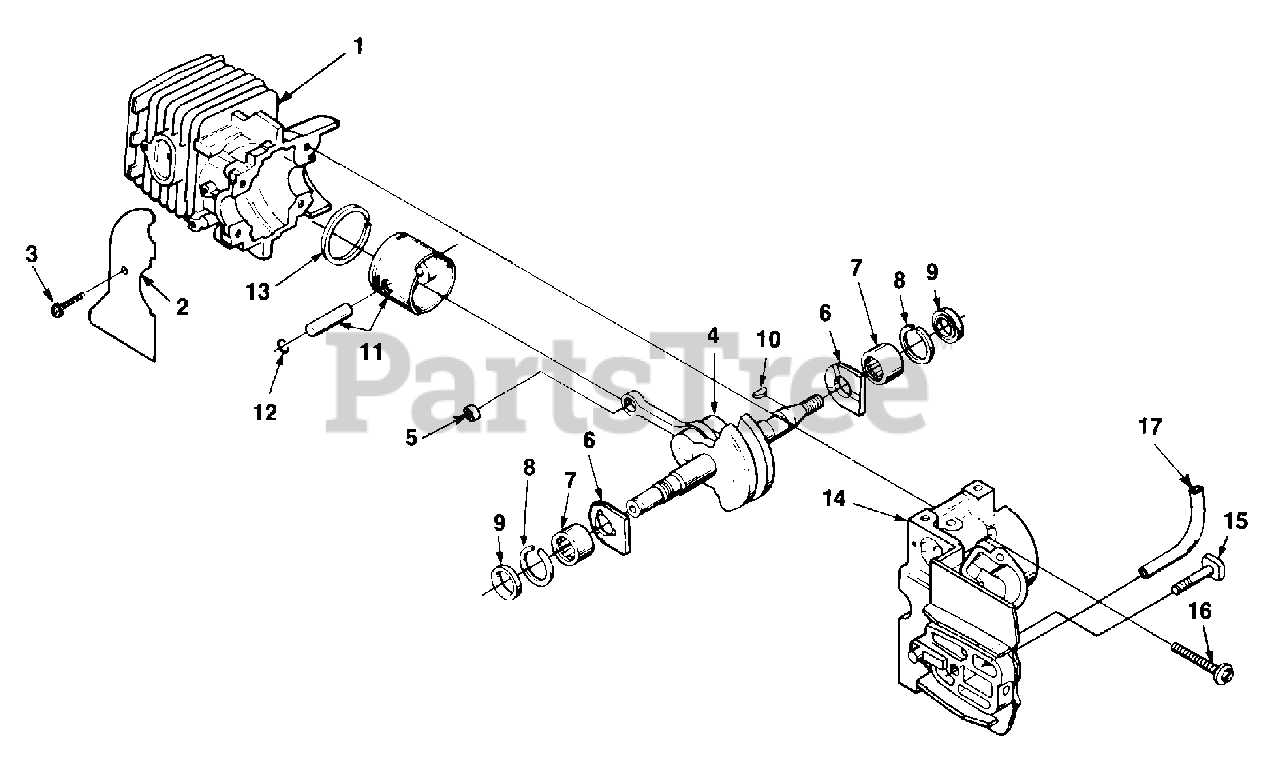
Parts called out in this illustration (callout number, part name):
1	CYLINDER
2	SHIELD- Sawdust
3	SCREW- Tapping (#6-32 x 5/16")
4	CRANKSHAFT
5	BEARING
6	WASHER- Thrust
7	BEARING- Needle
8	SPACER
9	SEAL- Shaft
10	KEY- Woodruff
11	PISTON ASSEMBLY
12	RING- Retaining
13	RING- Piston
14	CRANKCASE
15	BOLT- Guide bar
16	SCREW- Pan hd. (10-24 x 1 1/8")
17	TUBING- Rubber (10")
